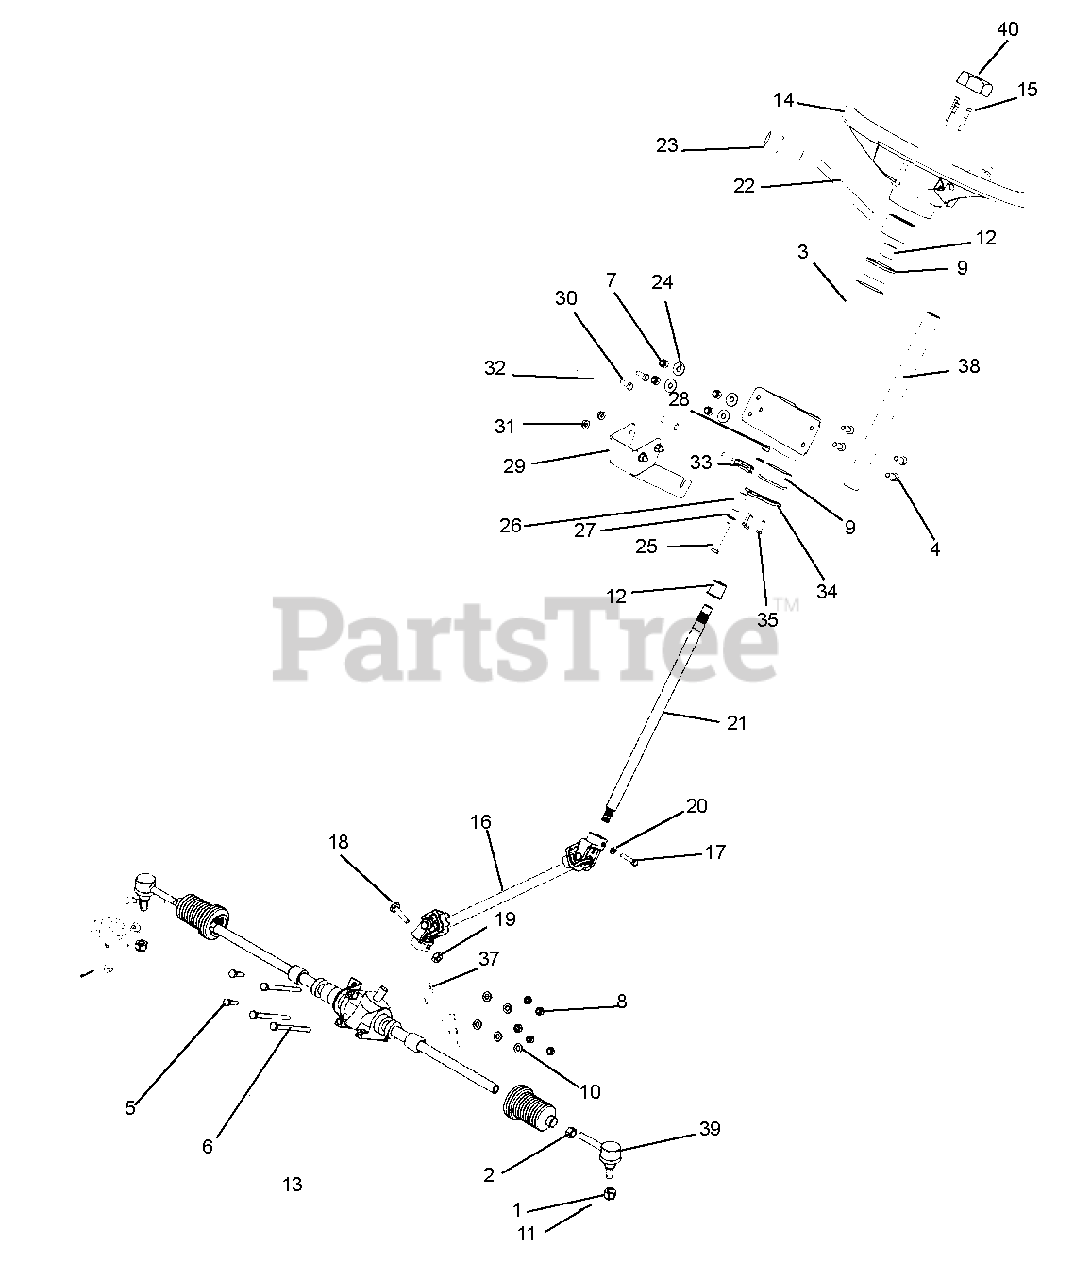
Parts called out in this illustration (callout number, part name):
1	NUT, HEX SLOTTED M12 X 1.25 YWZC
2	NUT, HEX M14 X 1.5 GR8.8 YWZC
3	STEERING COLUMN WELDMENT
4	BOLT, HEX .31-18 X .75 GR5 YWZC
5	BOLT, HEX .31-18 X 1.50 GR5
6	BOLT, HEX .31-18 X 4.50 GR5 YWZC
7	NUT, LOCK NYLOC .312-18 YWZC
8	NUT, LOCKING TOP FLANGE .31-18 YWZC
9	BUSHING, STEERING COLUMN, LARGE
10	WASHER, FLAT STEEL .38 X .875 X .083 YWZC
11	PIN, COTTER 3/32 X 1 LONG
12	BUSHING, STEERING COLUMN, SMALL
13	RACK & PINION ST
14	STEERING WHEEL, 3 SPK CONTOUR
15	BOLT, 10-24 X 1.25 SOCKET GR5 YWZC
16	STEERING SHAFT TRUCK
17	MVL BOLT FOR T840-093C
18	HHCS M10 X 1.5 X 35 PLT
19	NUT LOCK NYLOC M10 X 1.5 PLT
20	MVL SPRING WASHER FOR T840-093C
21	UPPER STEERING SHAFT TRUCK ASSEMBLY
22	WLDT, COLUMN SHIFT LEVER
23	SHIFTER KNOB
24	WASHER, FLAT STEEL .38 X .875 X .083 YWZC
25	BOLT, HEX .25-20 X 2.00 GR5
26	SHIFT STOP
27	WASHER, FLAT STEEL 281 X .62 X .065
28	NUT, LOCK NYLOC .250-20
29	CABLE BRACKET, SHIFTER
30	BOLT, HEX .25-20 X .75 GR5 YWZC
31	NUT, LOCKING FLANGE .25-20 YWZC
32	SHIFT CABLE (DASH)
33	YOKE 10-32 WITH LOCK
34	CAM, COLUMN SHIFTER
35	SHCS #10-24 X .750
37	SPACER, STEERING
38	SHAFT, COLUMN SHIFTER
39	TIE ROD END
40	NUT HEX M16X2.00X8MM THK PLT
